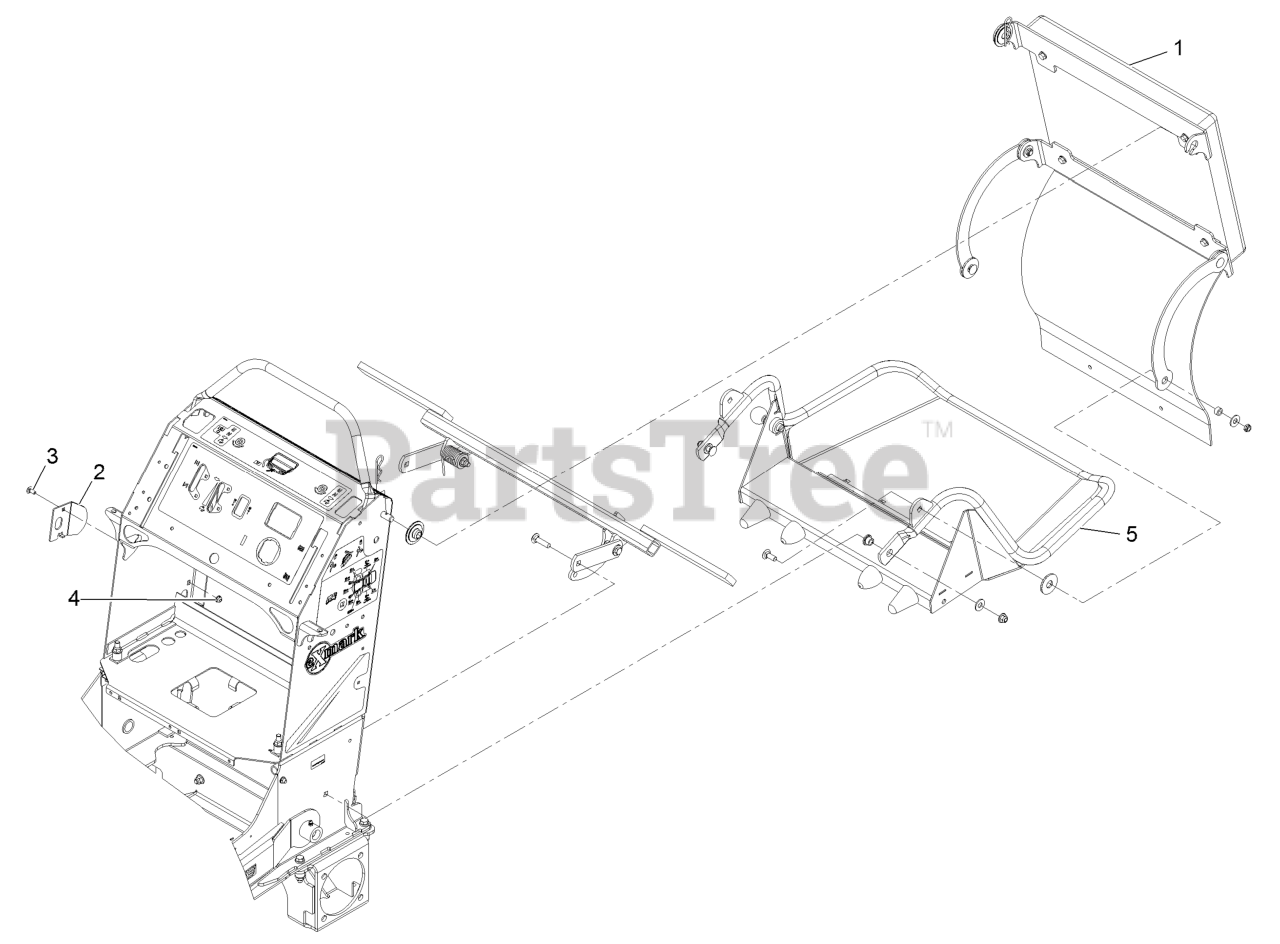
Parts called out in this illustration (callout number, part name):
1	ASM, Cushion
2	Plate-Striker
3	Bolt-Carriage 1/4-20 X 5/8
4	Nut-Nyloc 1/4-20 Flg
5	ASM,Platform
